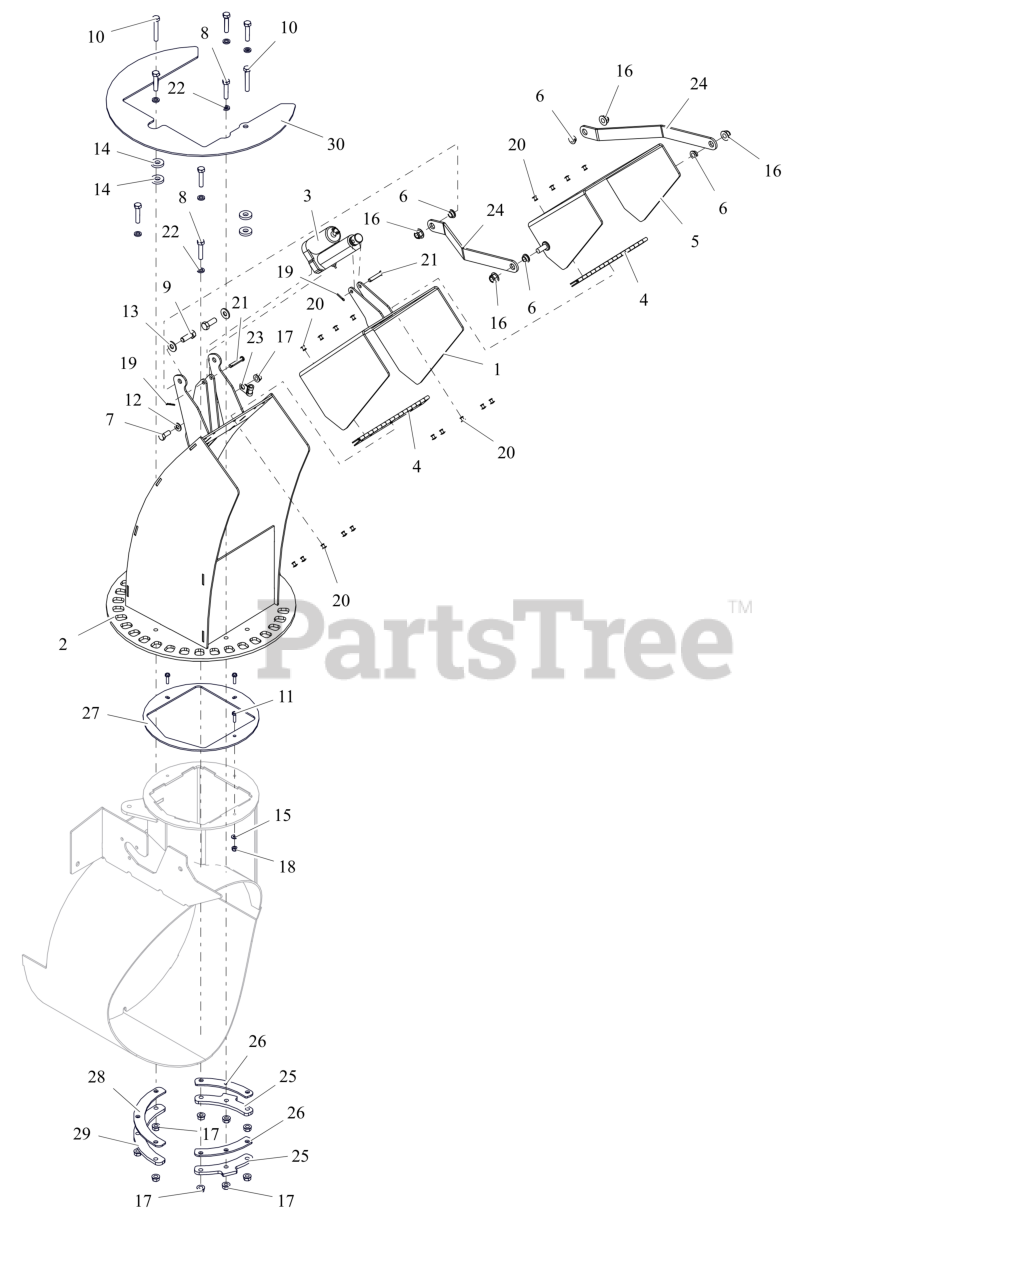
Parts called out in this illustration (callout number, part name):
1	WLDMT, MID CHUTE
2	WLDMT, LOWER CHUTE
3	ACTUATOR, CHUTE
4	HINGE, CHUTE
5	WLDMT, CHUTE CAP - W/DECAL
6	BEARING, FLANGE .375
7	BLT,HEX .31-18X.75 G5 ZCC
8	BLT, HEX .31-18X1.50 G5 ZCC
9	BLT,HEX .38-16X1.00 G5 ZCC
10	BLT, HEX .31-18X2.00 G5 ZCC
11	BLT, HWH #10-24X.75 ZCC
12	WSHR,FLT .344X.688X.065 ZCC
13	WSHR,FLT .375X.875X.083 ZCC
14	WSHR, FLT .406X1.00X.188 ZCC
15	WSHR, FLT .219X.500X.049 ZCC
16	NUT,NYL-FLG .38-16 GF ZCC
17	NUT,LK-CTR-FLG .31-18 GF ZCC
18	NUT-LK-NYL #10-24 G2 ZCC
19	PIN,CTR .09X.75 EXTPRSQCT ZCC
20	RVT, BLIND #64 .1875 X GRIP .188-.250 GR51
21	PIN, CLEVIS .25"X1.188" EL
22	WSHR, FLAT-STL .344X.562X.093
23	CLAMP, CABLE .250"
24	BRKT, CHUTE PIVOT
25	CLAMP, CHUTE STOP
26	WEAR, PAD CHUTE
27	BAFFLE, DISCHARGE NECK
28	WEAR, PAD CHUTE
29	CLAMP, CHUTE
30	PLATE, COVER - CHUTE
